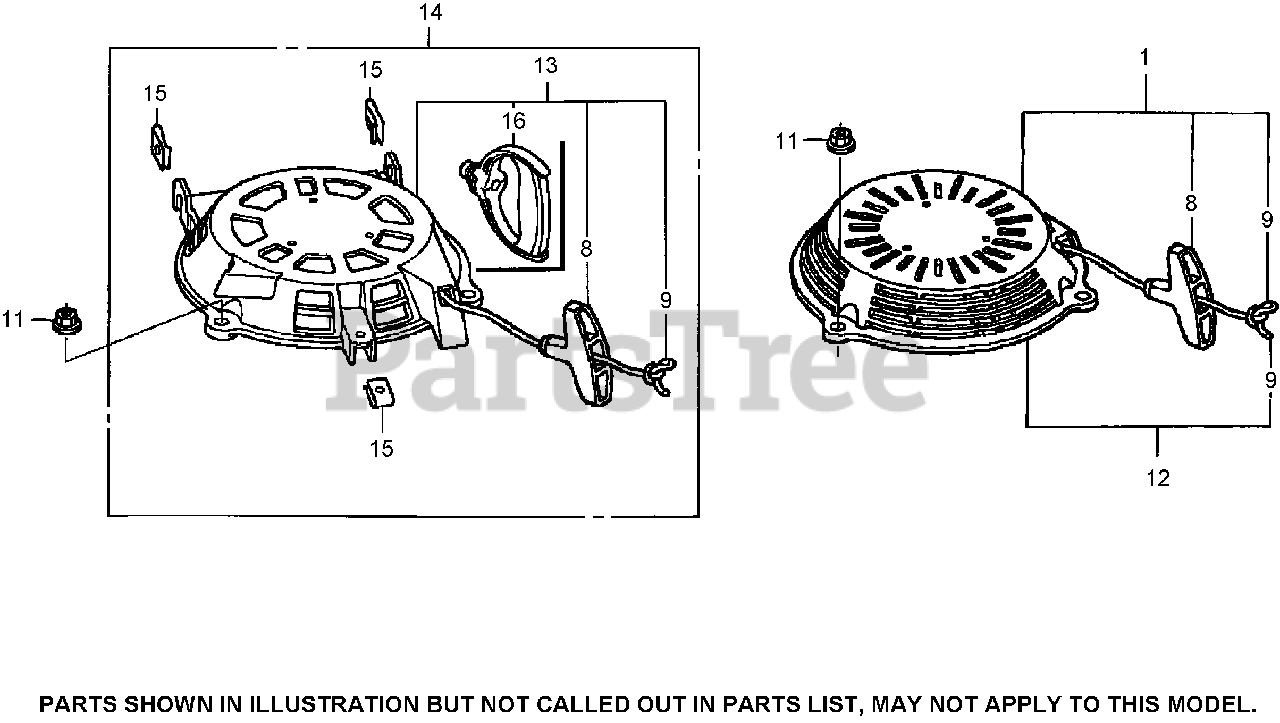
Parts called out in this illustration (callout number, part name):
9	ROPE, RECOIL STARTER
11	NUT, FLANGE (6MM)
13	STARTER ASM., RECOIL
15	NUT, COWL (UPPER)
16	KNOB, RECOIL STARTER
